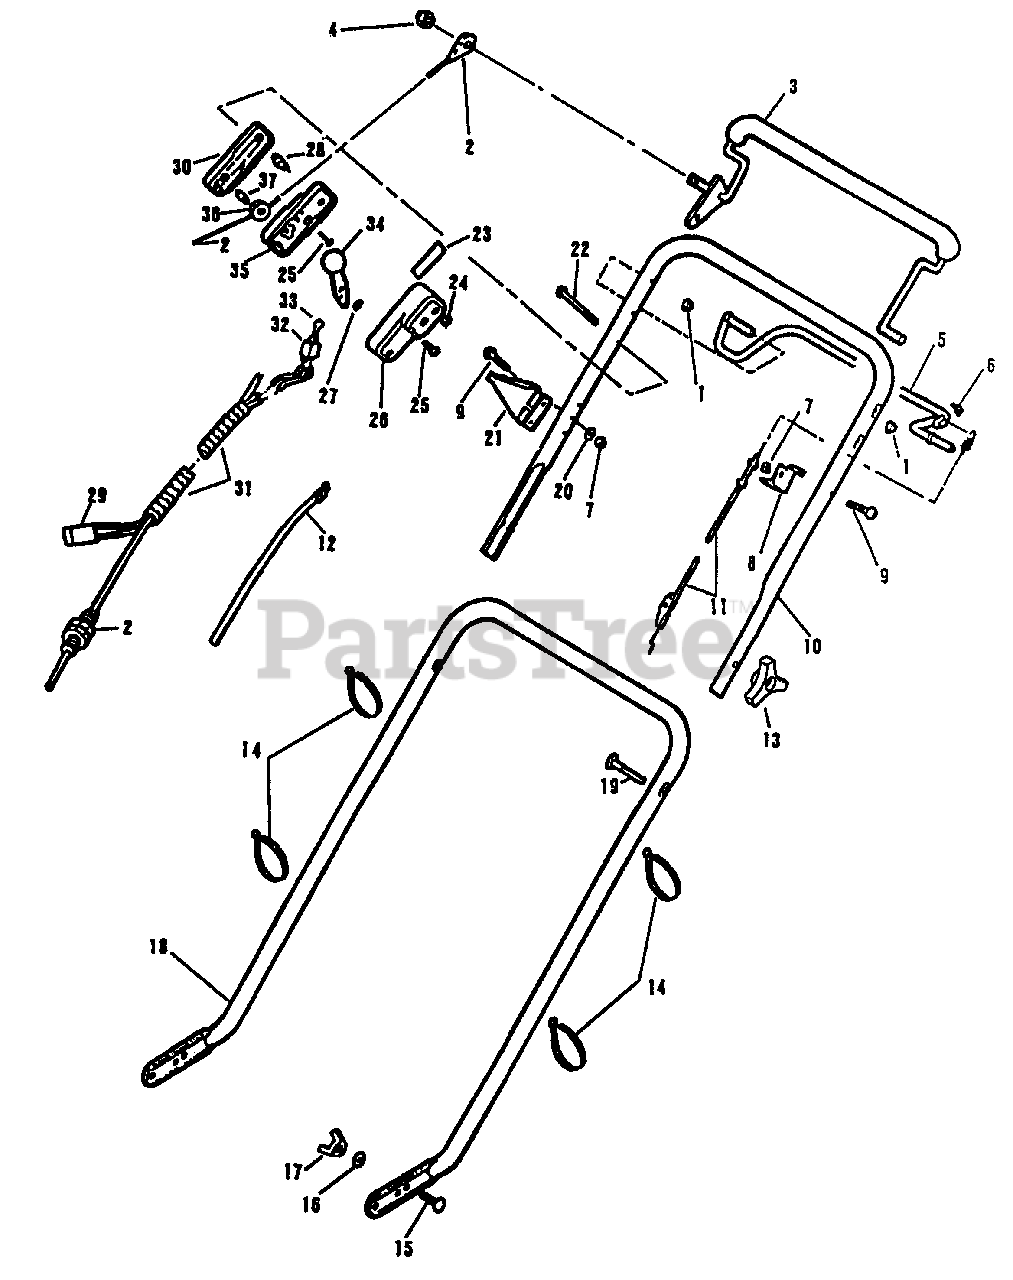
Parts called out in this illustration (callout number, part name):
1	Palnut
2	Control Cable Assembly
3	Control Lever Assembly
4	Acom Nut
5	Control Lever-Bail
6	Nut-Push On
7	Nut
8	Conduit Anchor
9	Screw
10	Handle Section-Top
11	Control Cable Assembly
12	Throttle Cable
13	Handle Knob
14	Tie Strap
15	Screw-Handle Mounting
16	Washer
17	Wing Nut
18	Handle Section-Lower
19	Screw-Folding Handle
20	Washer
21	Rope Guide
22	Screw
23	Decal-Throttle Control
24	Nut
25	Screw
26	Case-Throttle-Inner
27	Washer
28	Column
29	Wire Harness Assembly
30	Control Case-Outer
31	Spiral Tubing
32	Switch Assembly
33	Key
34	Lever and Knob Assembly
35	Case Throttle-Center
36	Pulley
37	Pin
